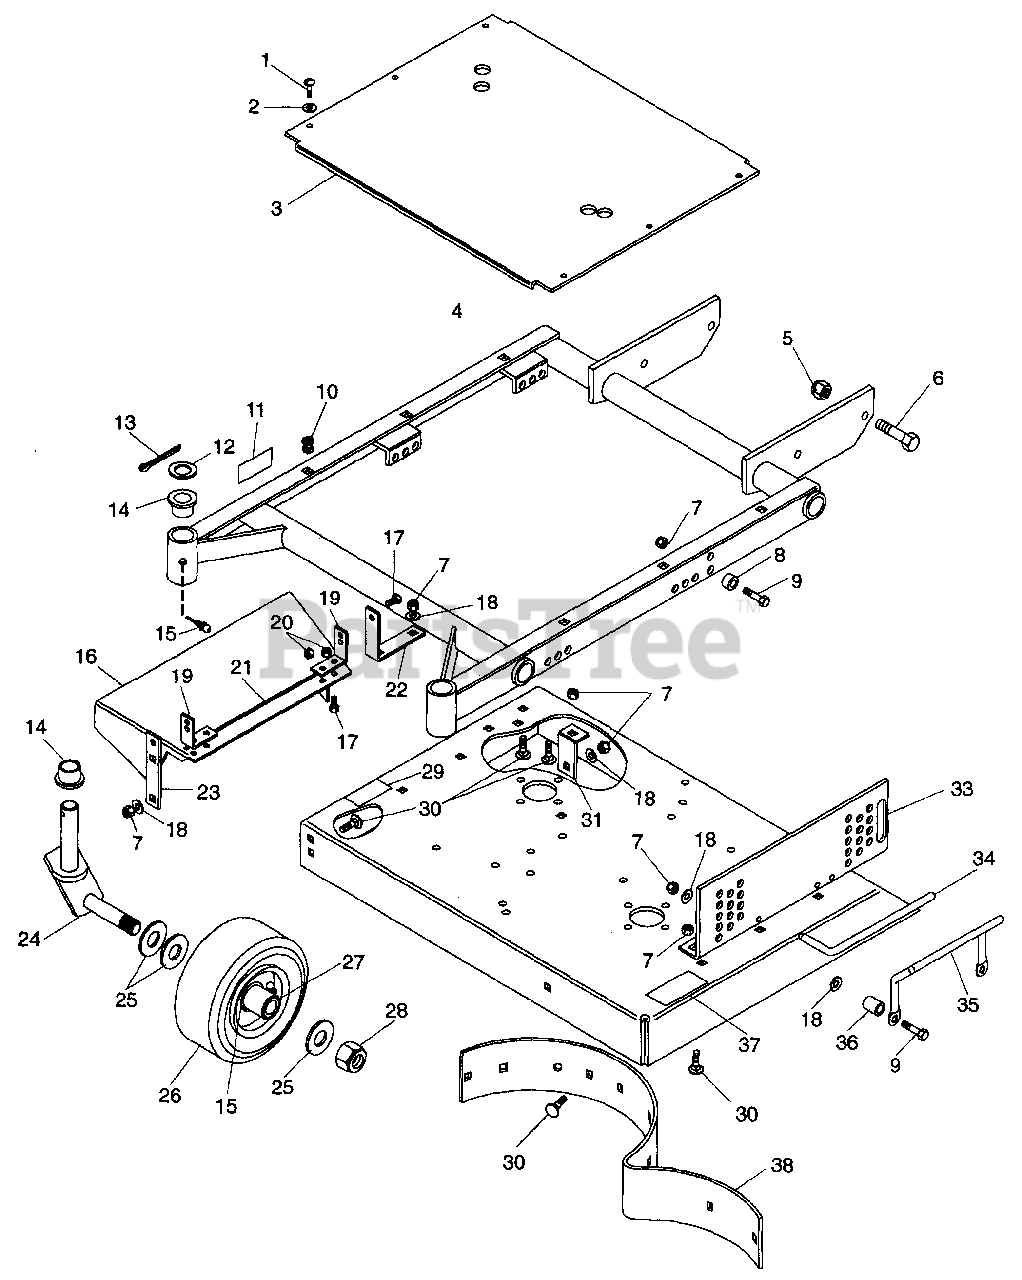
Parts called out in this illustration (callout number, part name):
1	Scr-Tap .25-20 x .50 Hxslhd Pl
2	Wshr-Fl-Stl .281 x .62 x .065 Pl
3	Cvr, Silkscreen 36" Mwr
4	Wldmt, Mwr Frm Multi-Mode
5	Nut-Lk-Nyl .625-11 Pl
6	Blt-Hex .625-11 x 1.50
7	Nut-Lk-Nyl .375-16 Pl
8	Bushing .391 x .626 x .670
9	Blt-Hex .38-16 x 1.50 Pl Gr 5
10	Gmmt, Plastic
11	Decal, Danger Hand
12	Brg-R-Thrst 1.002 x 1.552 x .030
13	Pin-Cotr .188 x 1.50
14	Bshg-FIg 1.010 x 1.385 x .75 x 1.75
15	Ftg-Lube .25-28 x .256
16	Chute, Discharge
17	Blt-Hex .31-18 x .75 Pl Gr 5
18	Wshr-Fl-Stl .406 x .812 x .065 Pl
19	Brkt
19	Brkt, Disch. Chute, 36",Limit Stop
20	Nut-Lk-Nyl .312-18 Pl
21	Width of Cut Decal
22	Brkt
23	Brkt
24	Wldmt Caster Fork
25	Wshr-Flat .812 x 1.469 x .134
26	Whl 9 x 3.50
27	Brg, Ball(Heim Sealed)
28	Nut-Lk-Nyl Insr.75-10 Pl
29	Decal, Waming Eye
30	Blt-Rdhdsqnk .38-16x 1.00
31	Brkt
32	Wldmt, 36" R.D. Deck
33	Brkt, Mwr Side Sprt L.H.
33	Brkt, Mwr Side Sprt R.H.
34	Pin, Mower Locking
35	Handle
36	Bushing
37	Decal, Danger Foot
38	Scroll
39	Decal, Gravely Logo
40	Decal, Pro-36
